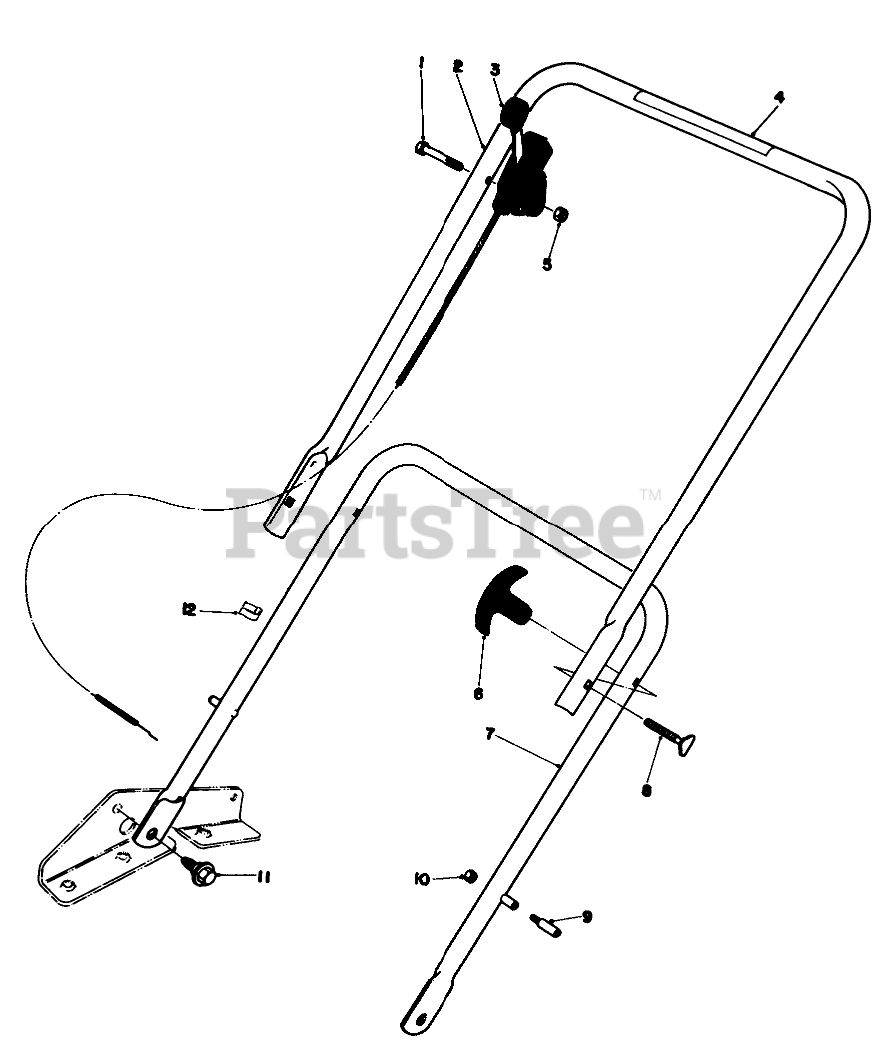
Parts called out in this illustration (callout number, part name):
1	SCREW-HH
2	Upper Handle
3	Throttle Control
4	Decal
5	NUT-LOCK
7	LOWER HANDLE ASM SP
8	HANDLE SCREW
9	HANDLE PIN
10	Nut
11	SCREW-SHOULDER
